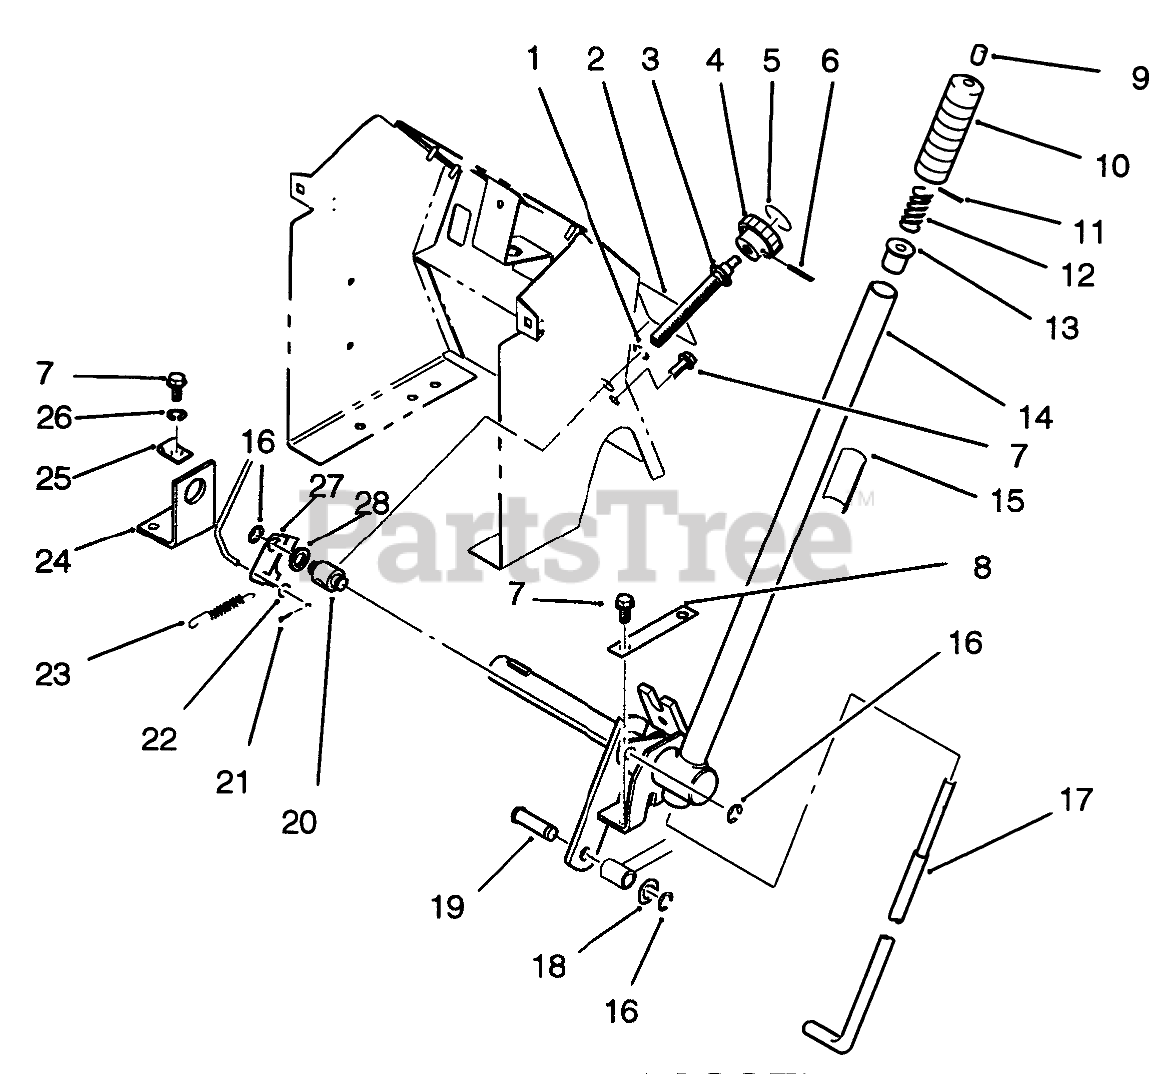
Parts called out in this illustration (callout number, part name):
1	Washer
2	DECAL-MWR ADJUST
3	ROD B
5	DECAL-HEIGHT KNOB
6	PIN-SPIROL
7	Screw
8	Plate
9	CAP-ROD, PLUNGER
10	HANDGRIP
11	PIN-SPIROL
11	Cotter Pin
12	SPRING-COMPRESSION
13	RETAINER-SPRING
14	Handle
15	DECAL-LIFT
16	RING-RETAINING, EXTERNAL
17	ROD-LATCH LIFT
18	WASHER-FLAT
19	ASS'Y-WHEEL & TIRE
20	TRUNNION
21	WASHER-FLAT
23	SPRING-EXTENSION
24	BRACKET B
25	THROTTLE CONTROL CLP
26	Washer-Lock
27	PLATE B
28	Washer
